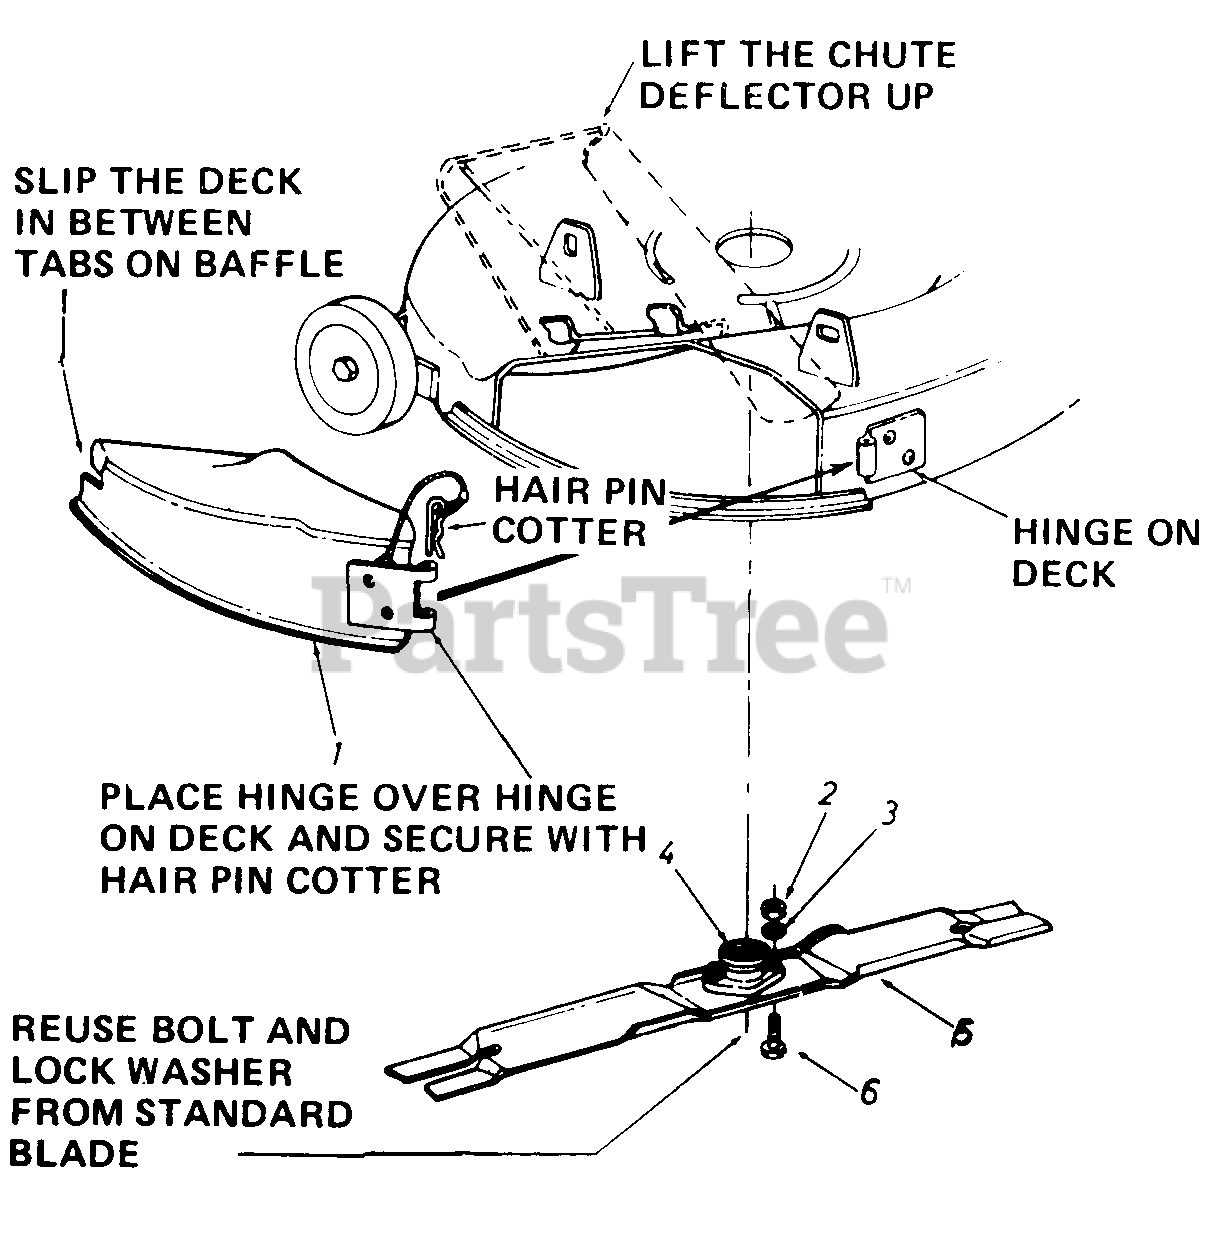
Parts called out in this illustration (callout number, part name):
1	30" Mulching Baffle Ass'y.
2	Hex Nut 5/16-24 Thd.*
3	L.-Wash. 5/16" I.D.*
4	Kit-Blade Adapter Ass'y.
5	30" Mulching Blade
6	Hex Bolt 5/16-24 x 1.0" Lg. H.T.
